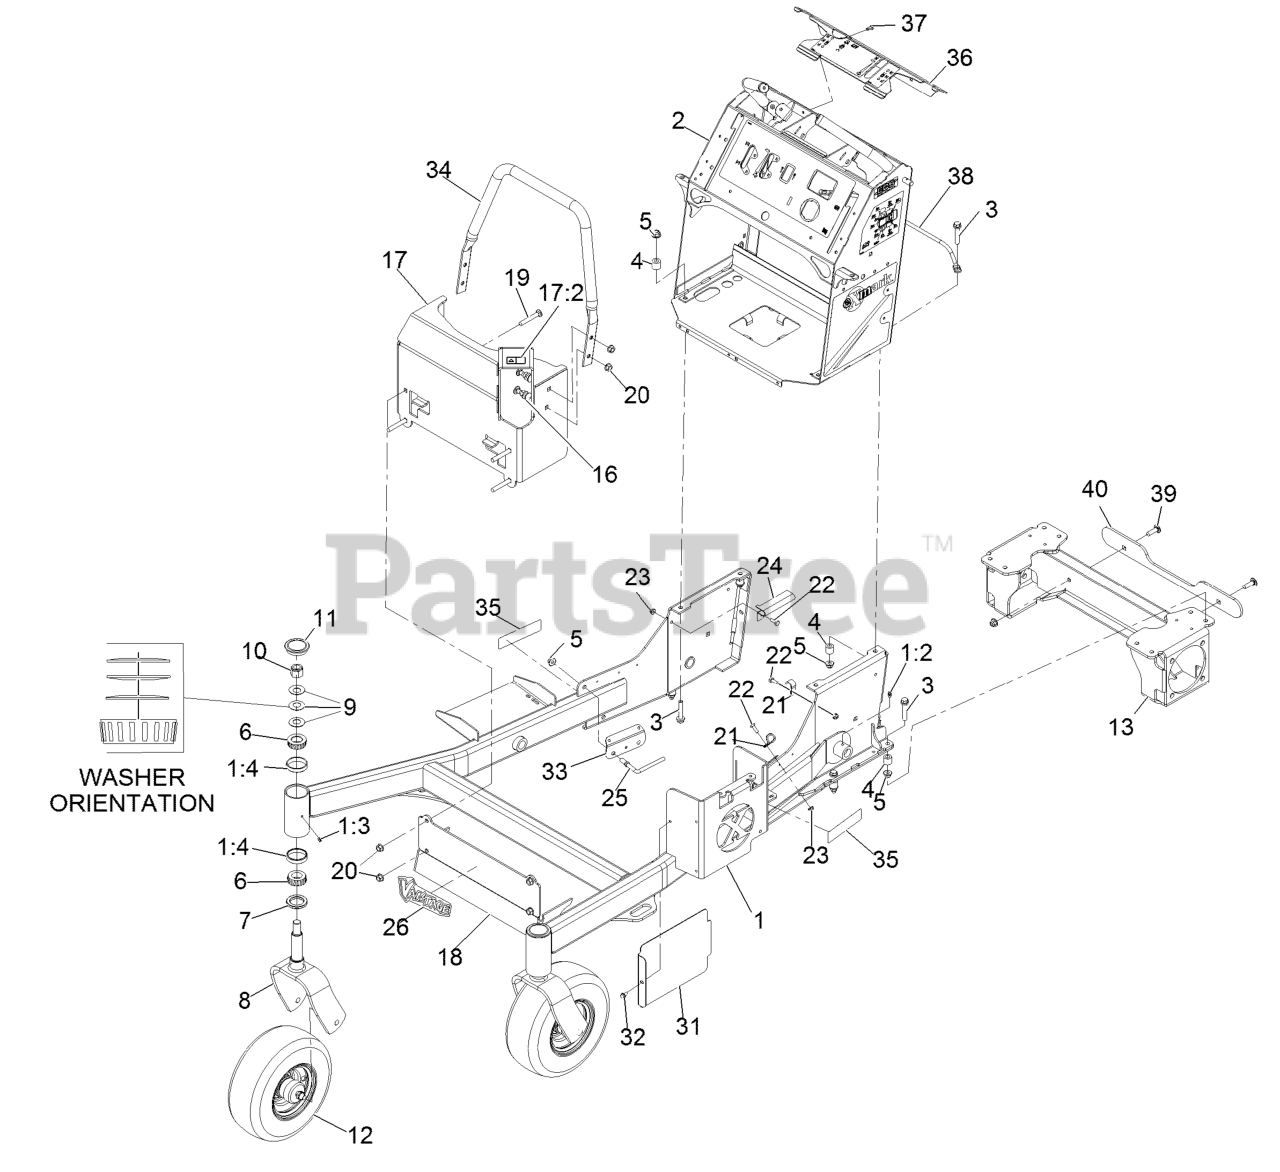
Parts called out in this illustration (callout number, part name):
1	FRONT FRAME ASM
1:2	FITTING-GREASE
1:4	CUP-BEARING
2	TOWER ASSEMBLY
3	SCREW-HHF
5	NUT-HF, NI
6	Cone-Bearing Tapered Roller
7	SEAL-GREASE
8	FORK-CASTER
9	WASHER-BELLVILLE
10	NUT-LOCK, NI
11	CAP-GREASE
12	WHEEL/TIRE AND BEARING AS
13	MOTOR FRAME WELDMENT
16	SCREW-CARR
17	ASM, MUFFLER GUARD W/ DEC
17:2	DECAL-WARNING
18	PANEL-GUARD
19	SCREW-CARR
21	CLAMP-CABLE
22	SCREW-HH
24	BRACKET-HOSE, FUEL (DOUBL
25	GUIDE-HOSE, SUPPORT
26	DECAL-VANTAGE LOGO
31	SHIELD-HEAT, TALL
32	SCREW-HWH
33	GUARD-HOSE
34	TUBE-GUARD
35	DECAL-X-SERIES
36	CONTROL PANEL W/DECALS
38	ROD, GUARD
39	SCREW-CARR
40	PLATE, BUMPER SPACER
